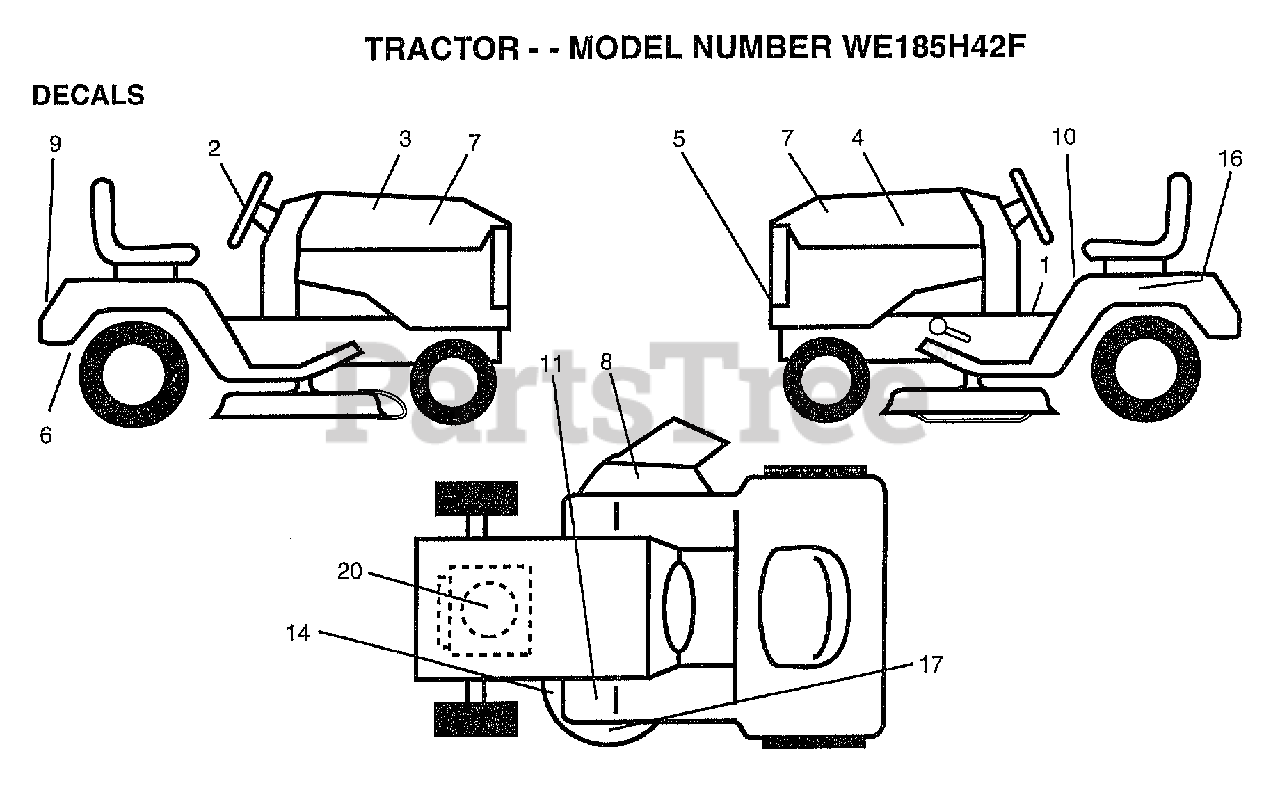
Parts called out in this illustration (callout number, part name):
1	DECAL SADDLE OPER
2	DECAL, INS STRG WH
3	DECAL.HOOD.RH.
4	DECAL.HOOD.LH
5	DECAL, GRILLE LENS
6	DECAL DRAWBAR LH
7	DECAL.PANEL.SIDE
8	"DECAL, WARNING"
9	DECAL.FENDER.LOGO
10	DECAL.CAUT.ENG/FR
11	DECAL T
14	"DECAL-SCHEM,BELT"
16	DECAL.BATRY.3-3908
17	DECAL, DECK GRASSEATER
20	DECAL.HP.ENGINE
